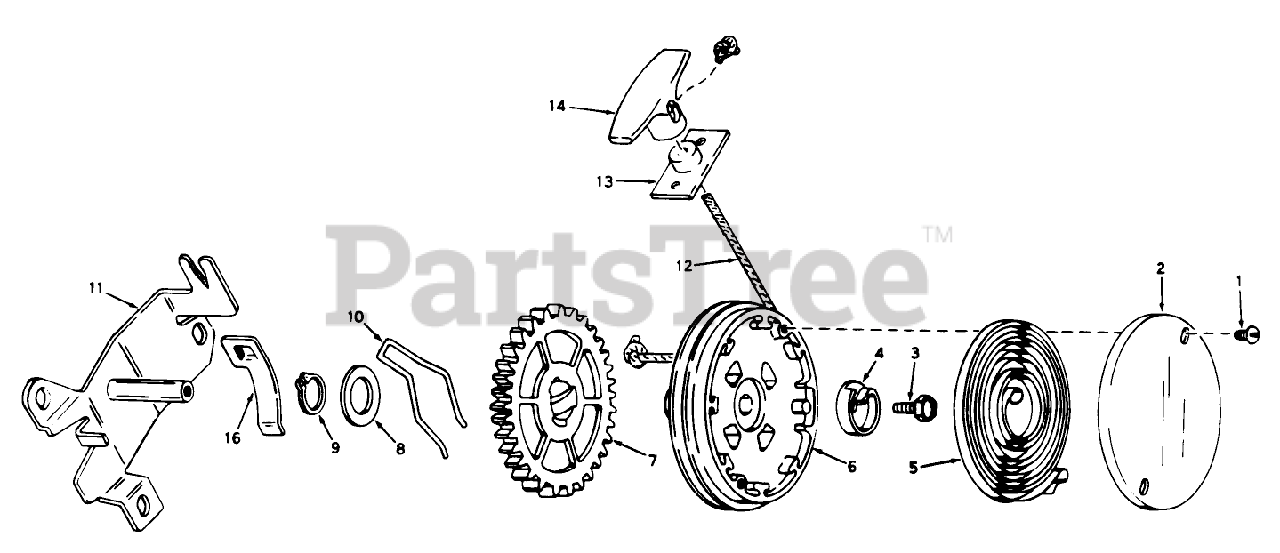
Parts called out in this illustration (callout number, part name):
1	Screw, Cover
2	Cover, Spring
3	Screw
4	Hub Spring
5	Spring, Rewind
6	Pulley
8	Washer
9	Ring, Snap
10	Brake
11	Bracket Assy. Mounting
12	Rope, Starter
13	Bracket Assy.
14	Handle-Starter
16	Clip Rope
